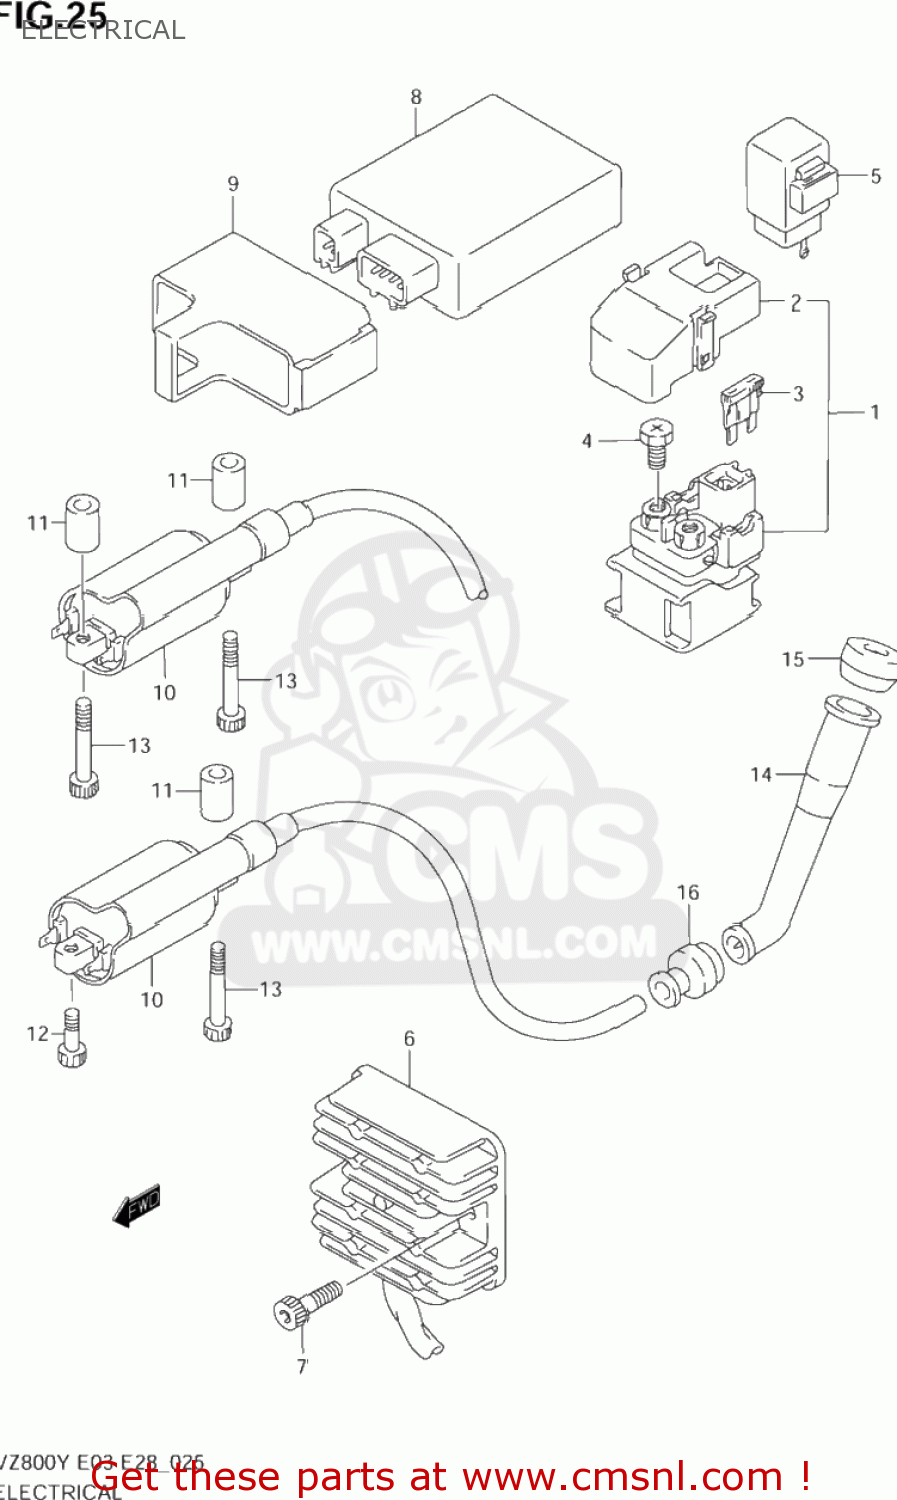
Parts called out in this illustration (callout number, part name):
1	RELAY ASSY,STARTING MOTOR
2	COVER,RELAY ASSEMBLY
3	FUSE(30A)
4	SCREW(6X8)
5	CONTROL UNIT,STG MOT RLY
6	RECTIFIER ASSY
7	BOLT,OIL FILLE
8	IGNITOR ASSY
9	CUSHION,IGNITOR
10	COIL ASSY,IGNITION
11	SPACER(6.2X12X16)
12	BOLT
13	BOLT
14	CAP,SPARK PLUG
15	SEAL,SPARK PLUG CAP
16	SEAL,HIGH TENSION CORD
